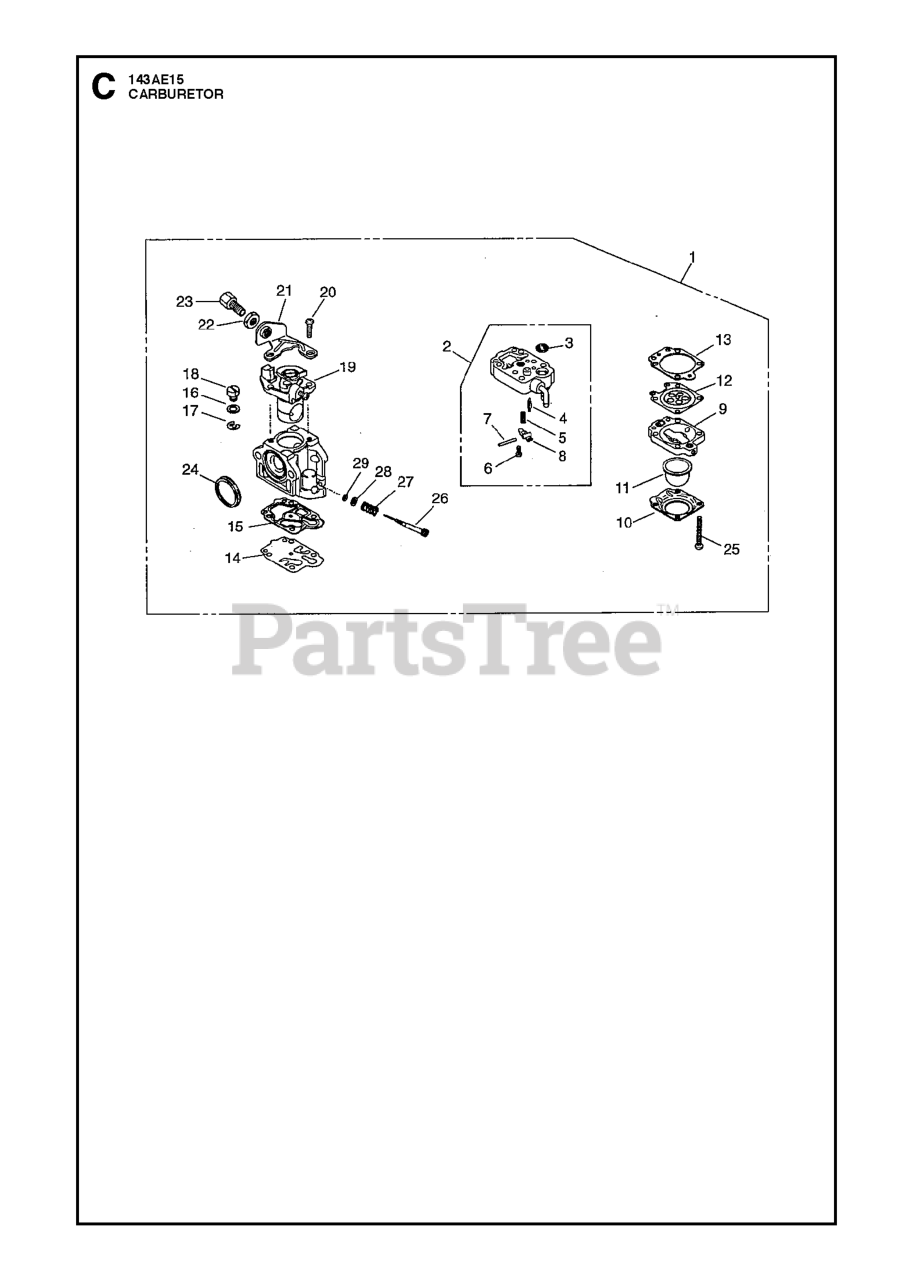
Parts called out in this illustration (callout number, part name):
1	CARBURETOR-A
2	CARBURETOR BODY
3	SCREEN
4	VALVE INLET
15	GASKET
22	NUT
24	RING PACKING
27	SPRING
